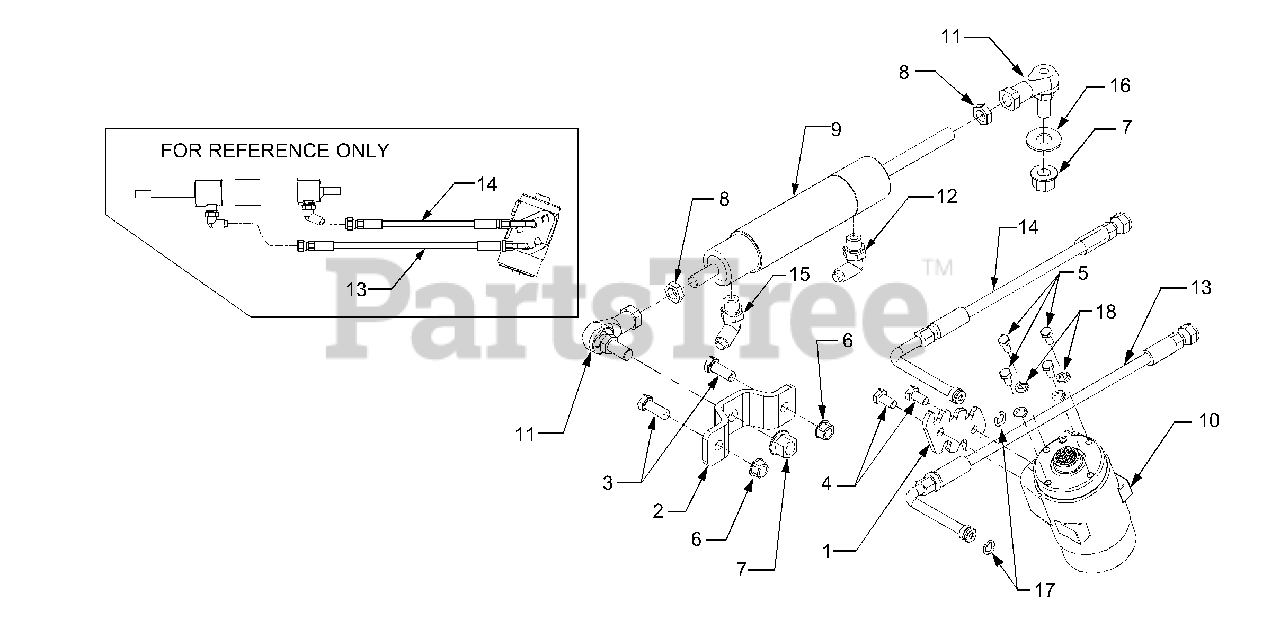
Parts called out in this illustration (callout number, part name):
1	Plate, Steering Pump Port
2	Bracket, Cylinder Mounting
3	Screw, Hex Cap 3/8-16 x 1.0 GR5
4	Screw, Hex Cap M8-1.25 x 16MM GR5
5	Screw, Hex Cap, M6 x 14MM
6	Nut, Hex Flange Lock, 3/8-16
7	Nut, Hex Flange Lock, M12 x 1.75
8	Nut, Hex, M12 x 1.75 RH
9	Cylinder, Steering
10	Pump, Hydraulic Steering
11	Ball Joint, 12MM x 1.75 RH
12	Fitting, 90 Degree Elbow
13	Hose, Front Steering
14	Hose, Rear Steering
15	Fitting, 45 Degree
16	Washer, Flat, .51 x 1.12 x .060
17	O-Ring, .426 x .566 x .070
18	Washer, Lock, 1/4"
